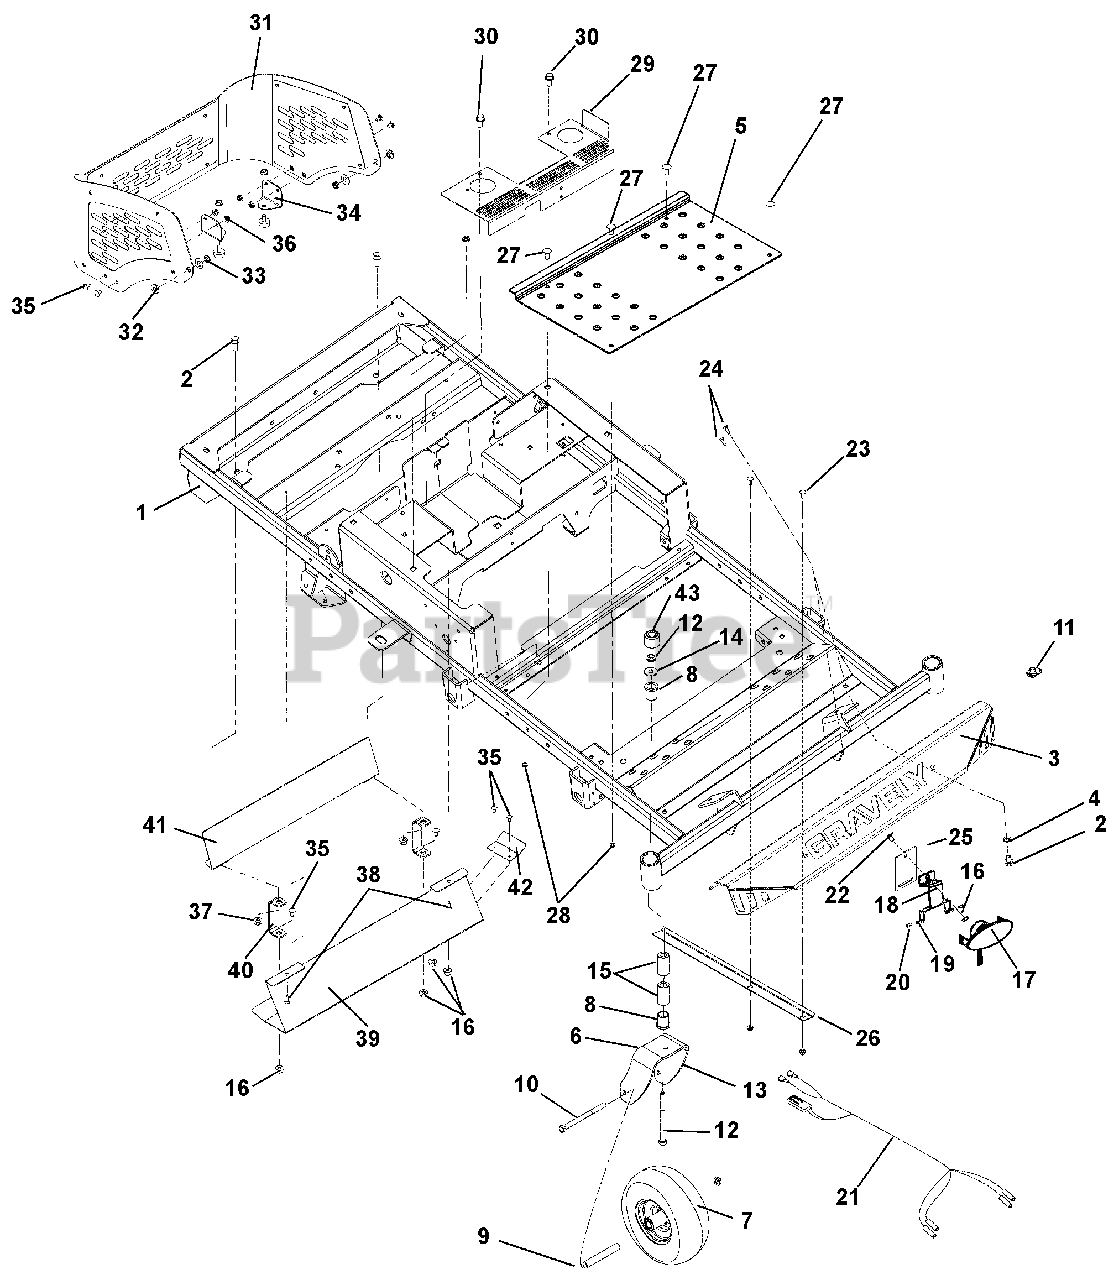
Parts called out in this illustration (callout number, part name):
1	Weldment, Frame XL
2	Bolt, Hex .38-16 x 1.00 Grade 5
3	Weldment, Footrest
4	Washer, Locking .38 x .094 Regular
5	Deck Access Panel
6	Fork, Caster
7	Wheel/Tire Assembly, 11.0 x 4.0 x 5.0
8	Bushing, Flange 1.00 x 1.25 x 1.50 x 1.50
9	Spacer, Rolled Wheel
10	Bolt, Hex .50-13 x 6.50 Grade 5
11	Nut, Retainer .375-16 x .37
12	Nut, Locking Top Flange .50-13
13	Bolt, Hex .50-13 x 5.00 Grade 5
14	Washer, Flat Steel .511 x 1.441 x .125
15	Spacer, Caster
16	Nut, Locking Top Flange .25-20
17	Assembly, Light
18	Bracket, Light
19	Nut-Locking-Nylon 10-24 with Insert
20	Screw-Machine 10-24 x .5 Hex Washer Head
21	Harness, Mini-Z Headlight
22	Bolt, Round Head Square Neck .25-20 x .75 Grade 5
23	Bolt, Round Head Square Neck .31-18 x .75 Grade 5
24	Bolt, Hex .25-20 x .75 Grade 5
25	Bracket, Light Mount
26	Bracket, Light Harness
27	Bolt, Hex .31-18 x 1.00 Grade 5
28	Nut, Locking-Nylon-Flange .31-18
29	Bracket, XL CE Fan Guard
30	Screw, Tapping .38-16 x .50 Hex Washer Head Thread Rolling
31	Assembly, Engine Wrap XL
32	Bushing, Flange .325 x .499 x .3 x .875
33	Nut, Locking Center Flange .31-18
34	Bracket, XL Engine Wrap Foot
35	Bolt, Round Head Square Neck .25-20 x .50
36	Nut, Locking Center Flange .25-20
37	Nut, Locking Top Flange .38-16
38	Screw, Tapping .25-20 x .50 Hex Washer Head Thread Rolling YWZ (Lubricated or Waxed)
39	Guard, Muffler Heat
40	Strap, Muffler Guard
41	Shield, Hot Surface
42	Deflector, Heat Shield
43	Cap, Dust
